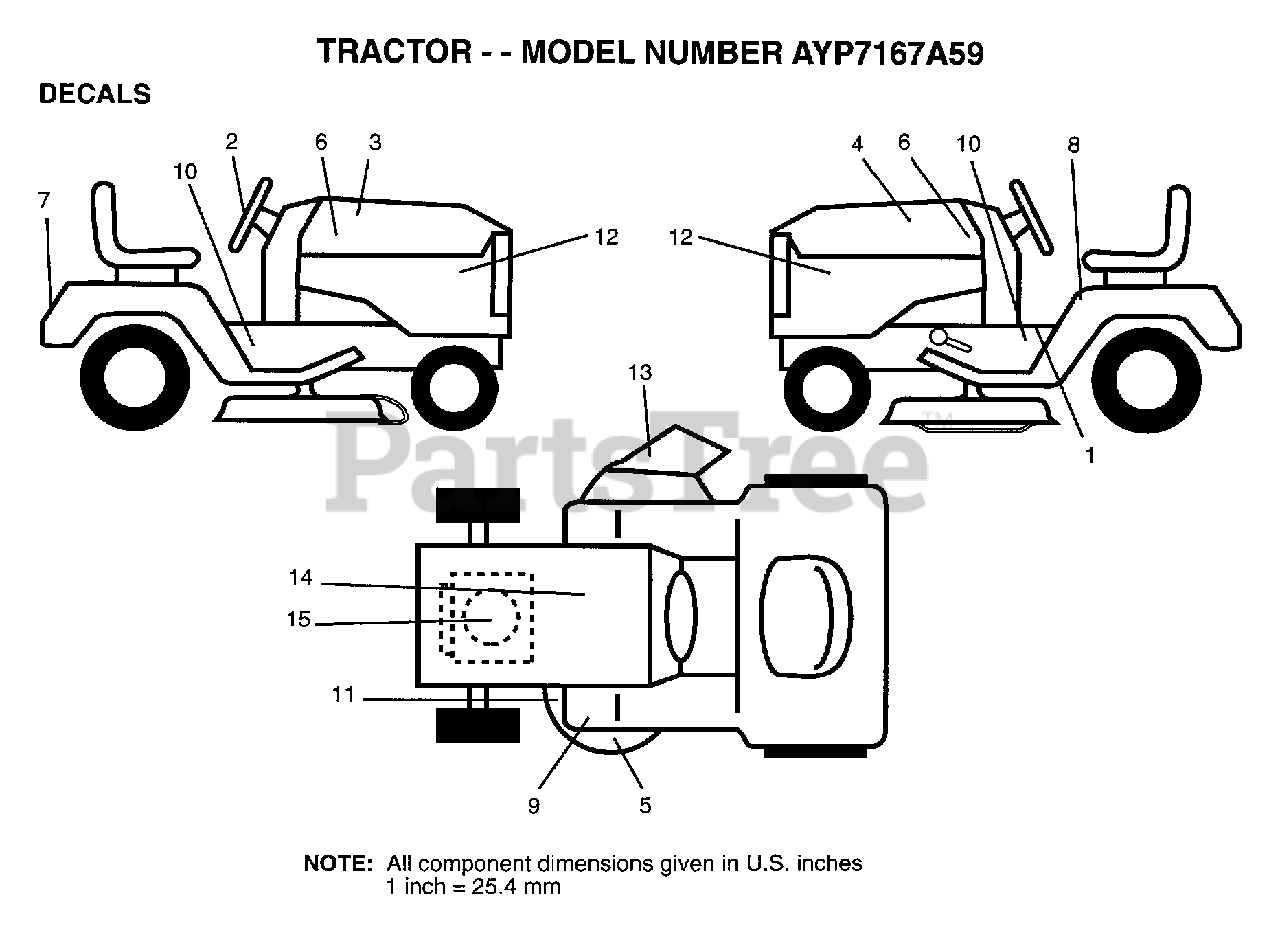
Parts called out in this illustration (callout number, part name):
2	DECAL STEER WHL
3	DECAL HOOD RH
4	DECAL HOOD LH
5	DECAL DECK WIZ +
6	NAMEPLATE.HD.WIZA
8	DECAL
10	DECAL CHASSIS WIZ
11	DECAL
12	DECAL.PNL.SIDE.VG
13	DECAL DECK MULCH
14	DECAL.BATRY.3-3908
15	DECAL.ENG.805720
